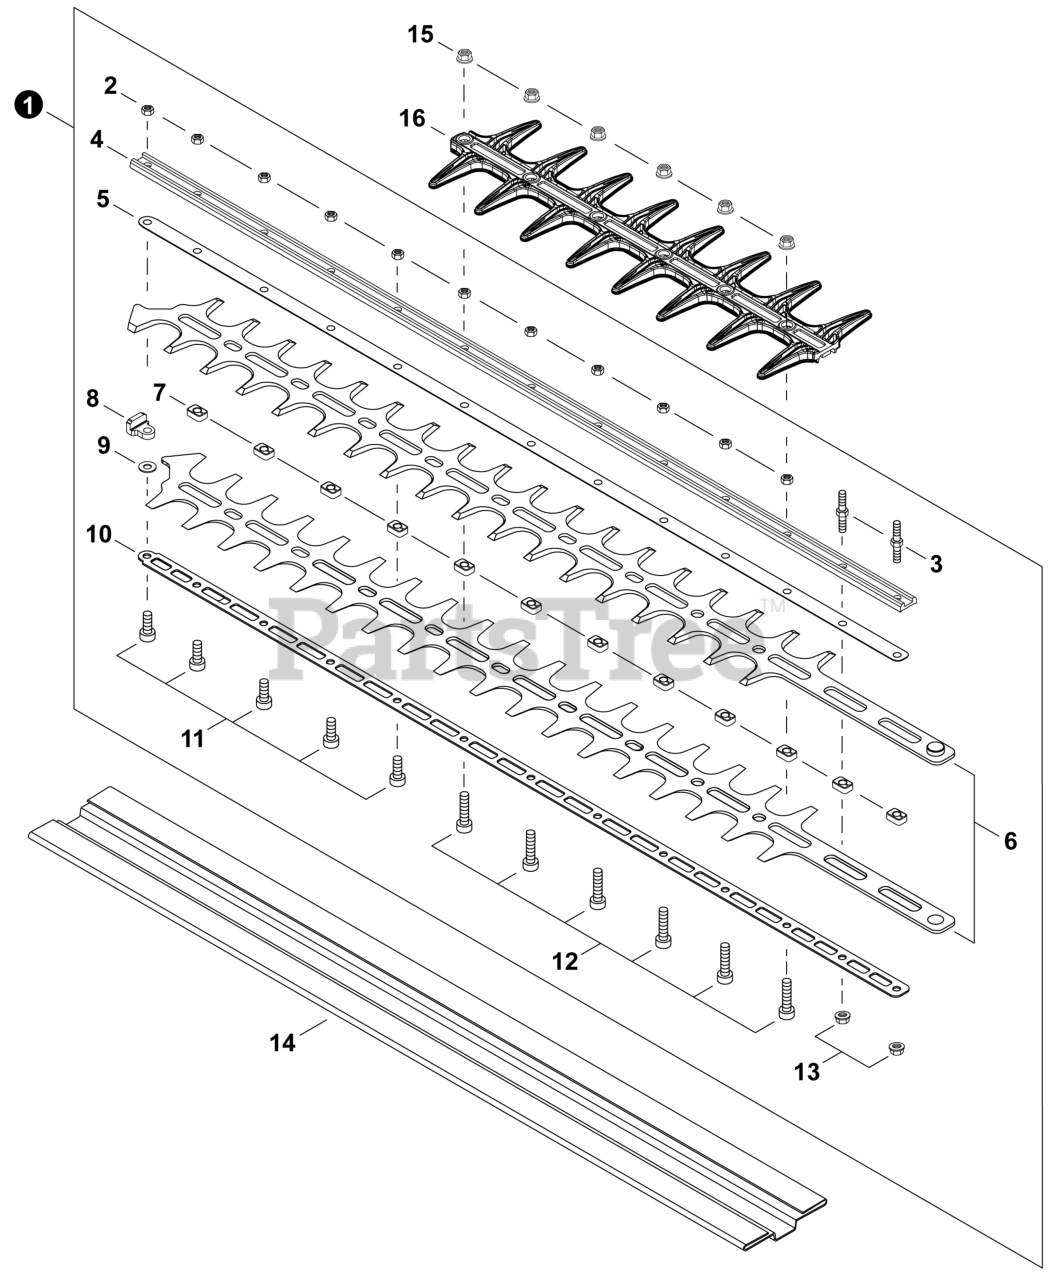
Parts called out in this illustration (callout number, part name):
1	CUTTER ASSY, 30"
3	STUD, MOUNTING M5x36
4	SUPPORT, BLADE 28"
5	SUPPORT, BLADE 28"
6	CUTTER 30"
10	SUPPORT, BLADE 30"
11	BOLT, TORX 5x16
12	BOLT, TORX 5x25
13	NUT, FLANGE M5
14	SCABBARD
15	NUT, FLANGE M5
16	GUARD, CUTTER BLADE
